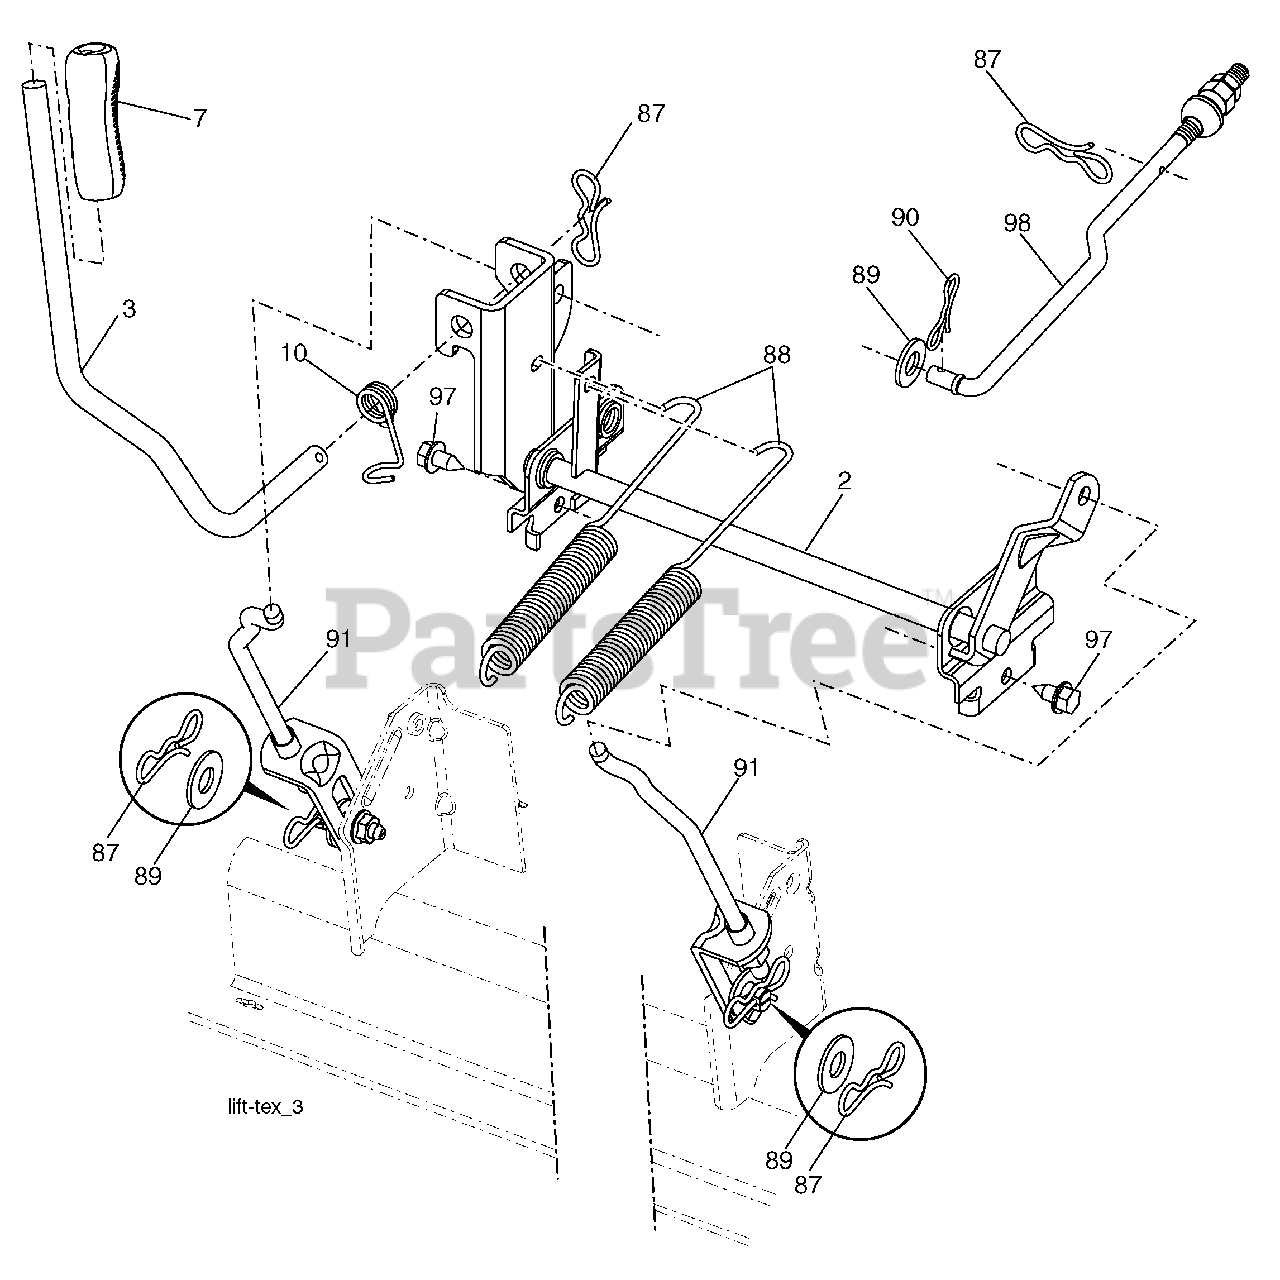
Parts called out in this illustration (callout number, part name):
2	Shaft Asm., Lift
3	Lever Asm., Lift RH
7	Grip, Lever
10	Spring Torsion
87	Pin Cotter 7/16 Bow Tie Lock
88	Spring Lift Assist
89	Washer Clear Zinc
90	Pin Cotter 5/16 Bow Tie Lock
91	Link Lift Susp Mower Rear
97	Screw 3/8-16 x 3/4
98	Link Lift Susp. Front Mower
